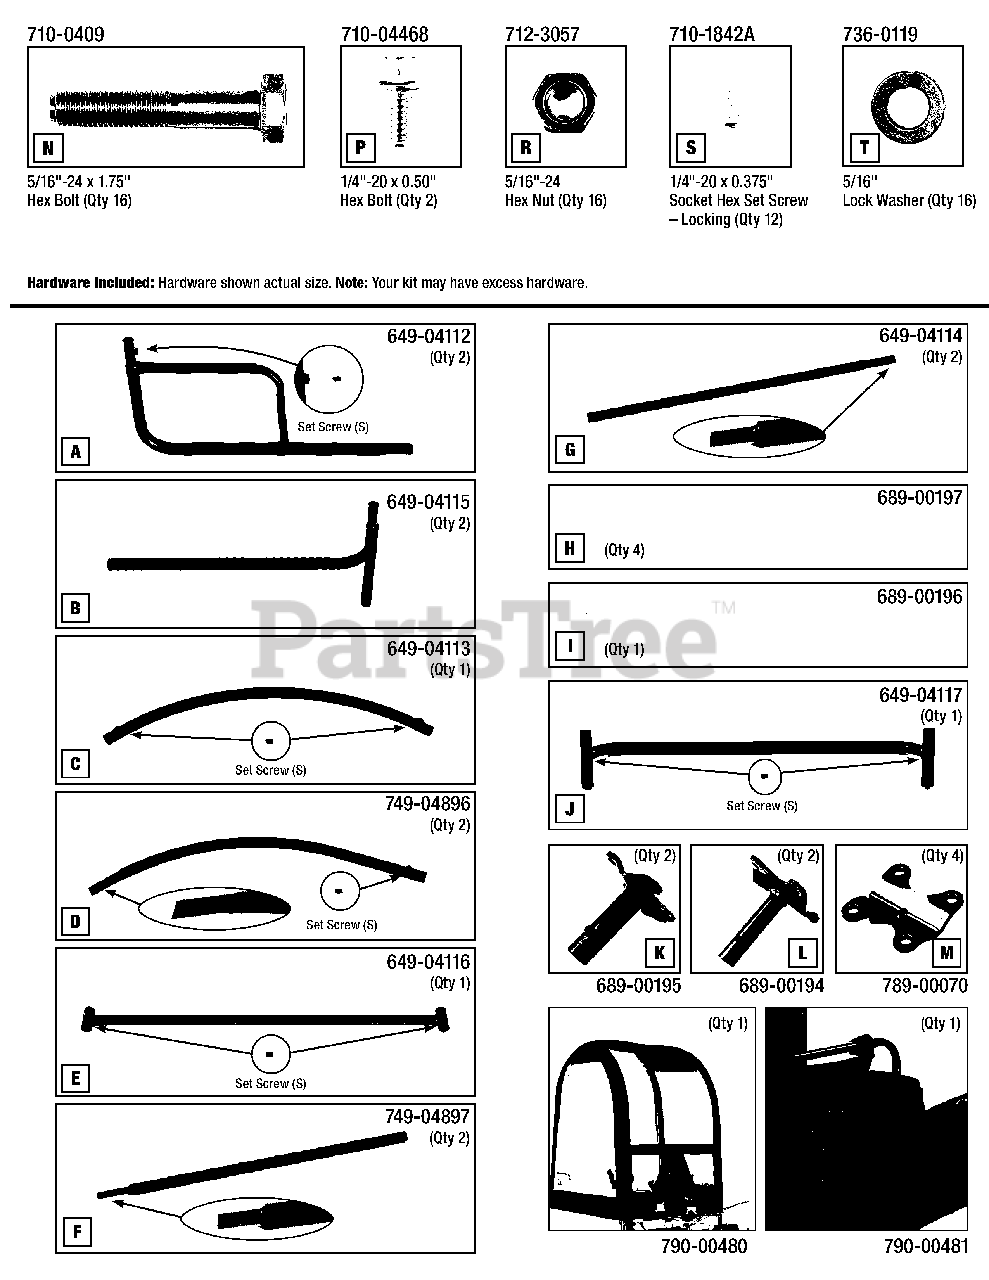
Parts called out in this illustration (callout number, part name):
A	REAR CORNER BAR
B	BAR-FRONT CORNER
C	ARC CENTER BAR
D	ARC END BAR LH & RH
E	CROSSBAR POLE
F	POLE-UPRIGHT FRONT
G	POLE-UPRIGHT REAR
H	FEXIBLE ROD
I	FLEXIBLE ROD-CENTE
K	TUBE/CLAMP ASM-FEM
L	TUBE/CLAMP ASM-MAL
N	SCREW-HEX 5/16-24
P	SCREW-HEX FLANGE
R	NUT-5/16X 24
S	SCREW-SET PATCH LOC 1/4-20 X .38
T	WASHER-LOCK 5/16
